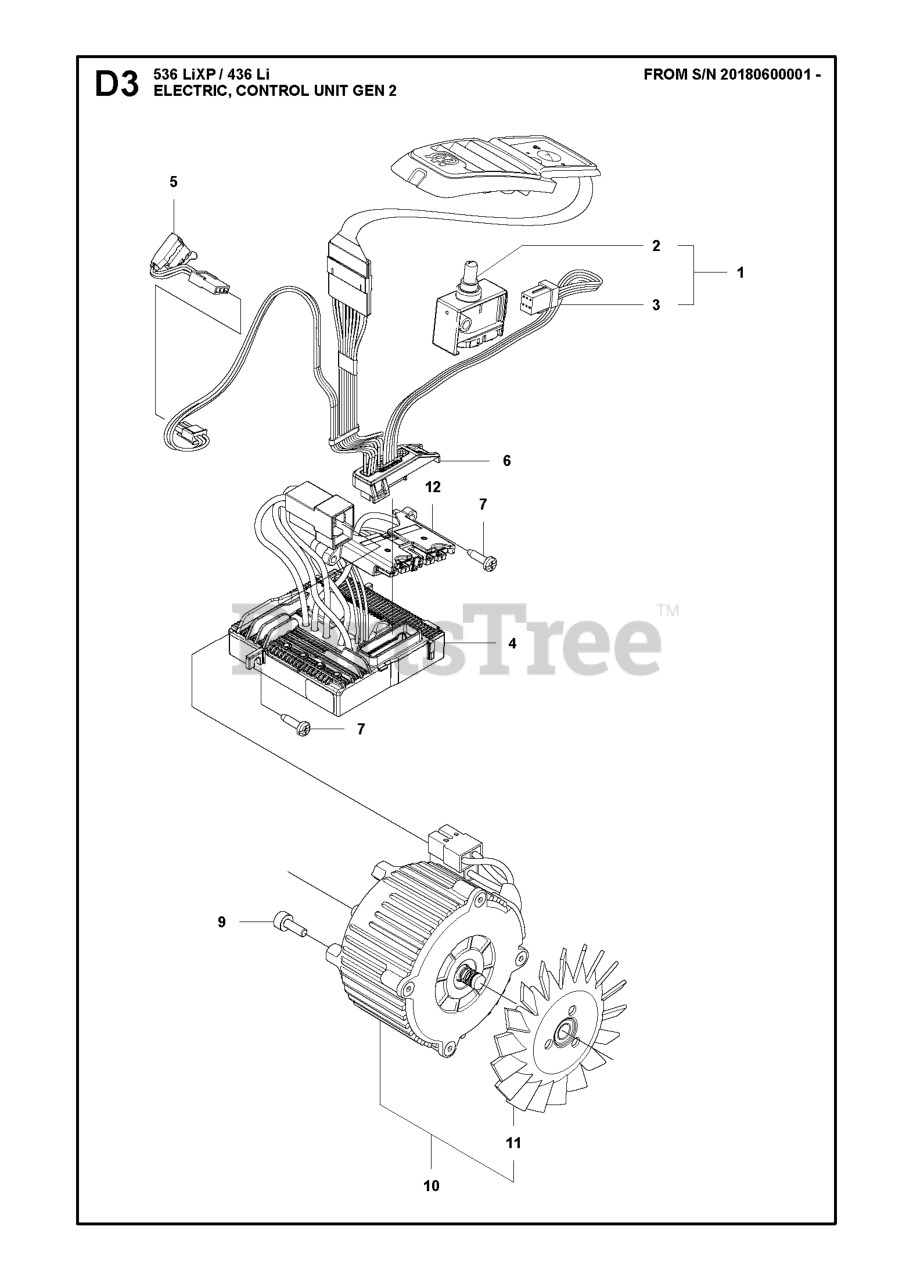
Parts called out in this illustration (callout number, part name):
1	SWITCH KIT BATTERY REAR HANDLE
2	TRIGGER SWITCH IPX4
3	WIRING ASSY SIGNAL REARHANDLE
4	CONTROL UNIT
5	WIRING ASSY
10	MOTOR ASSY BLDC D70
12	CONNECTOR BATTERY
